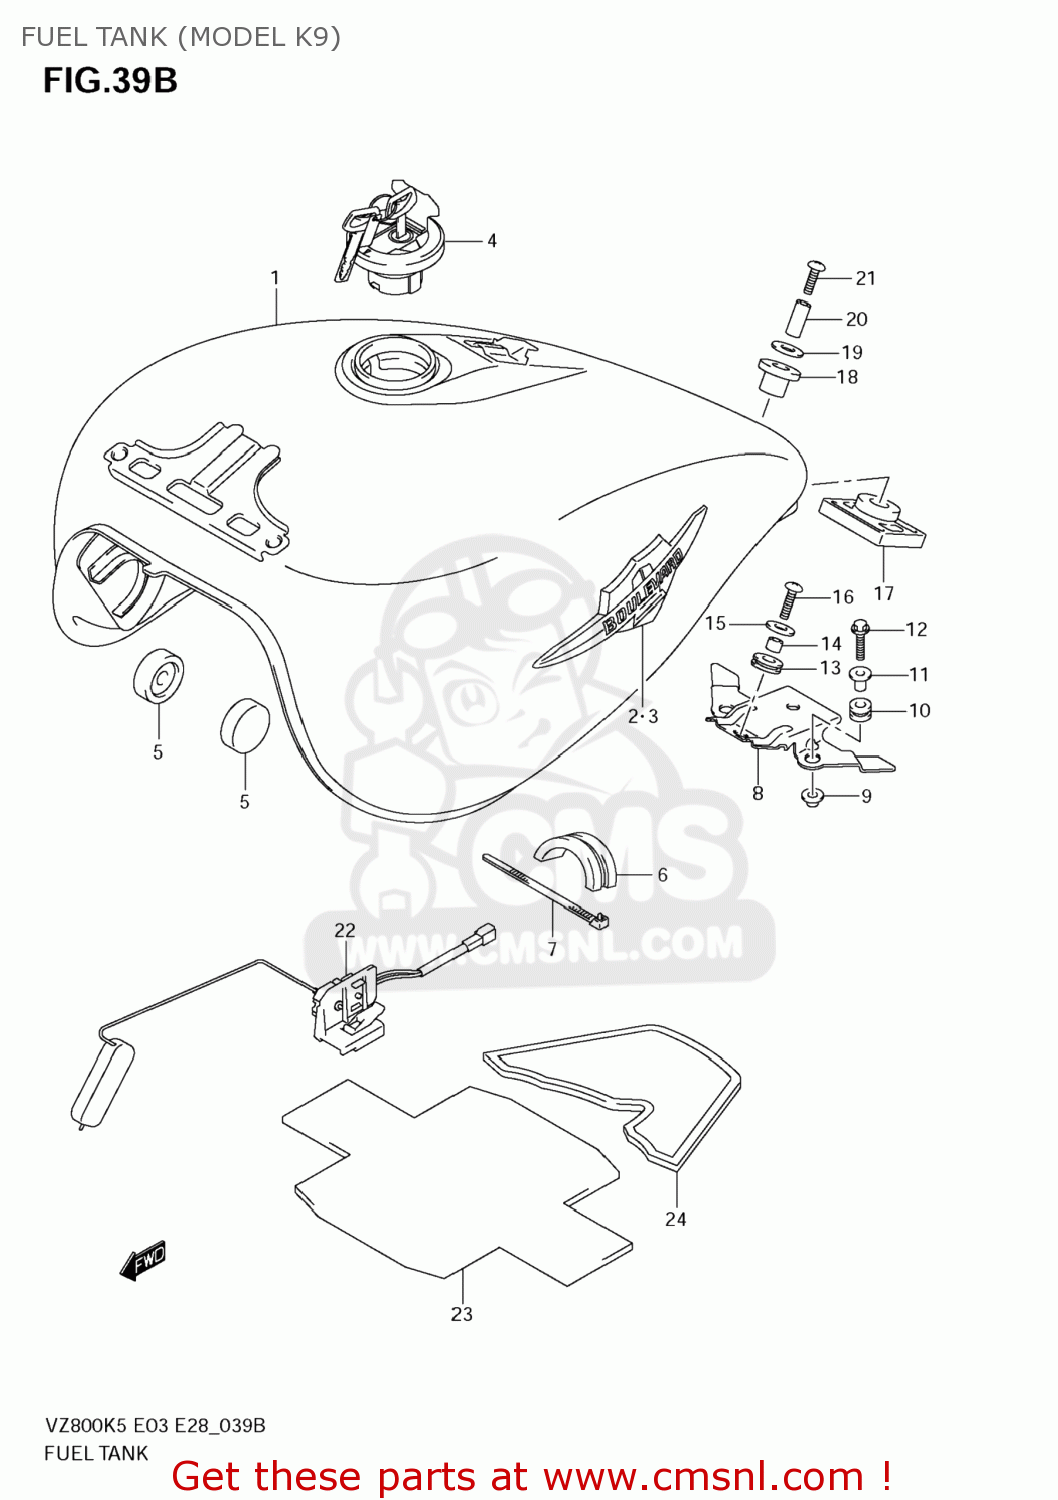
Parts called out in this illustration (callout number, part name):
1	TANK ASSY,FUEL
2	EMBLEM,FUEL TANK,R
3	EMBLEM,FUEL TANK,L
4	CAP SET,FUEL TANK
5	CUSHION
6	CUSHION,FUEL TANK LWR
7	CLAMP(L:250)
8	BRACKET,FUEL TANK RR
9	WASHER
10	CUSHION
11	WASHER
12	SCREW
13	CUSHION
14	SPACER(8.5X12X7.5)
15	WASHER(8.5X26X1.6)
16	BOLT(8X20)
17	CUSHION,FUEL TANK RR LWR
18	CUSHION,FUEL TANK RR UPR
19	SPACER (8.2X12.5X23.5)
20	WASHER (8.5X33X1.6)
21	BOLT
22	GAUGE ASSY,FUEL LEVEL SENDER
23	SHIELD,FUEL TANK HEAT
24	SHIELD,FUEL TANK HEAT NO.2
